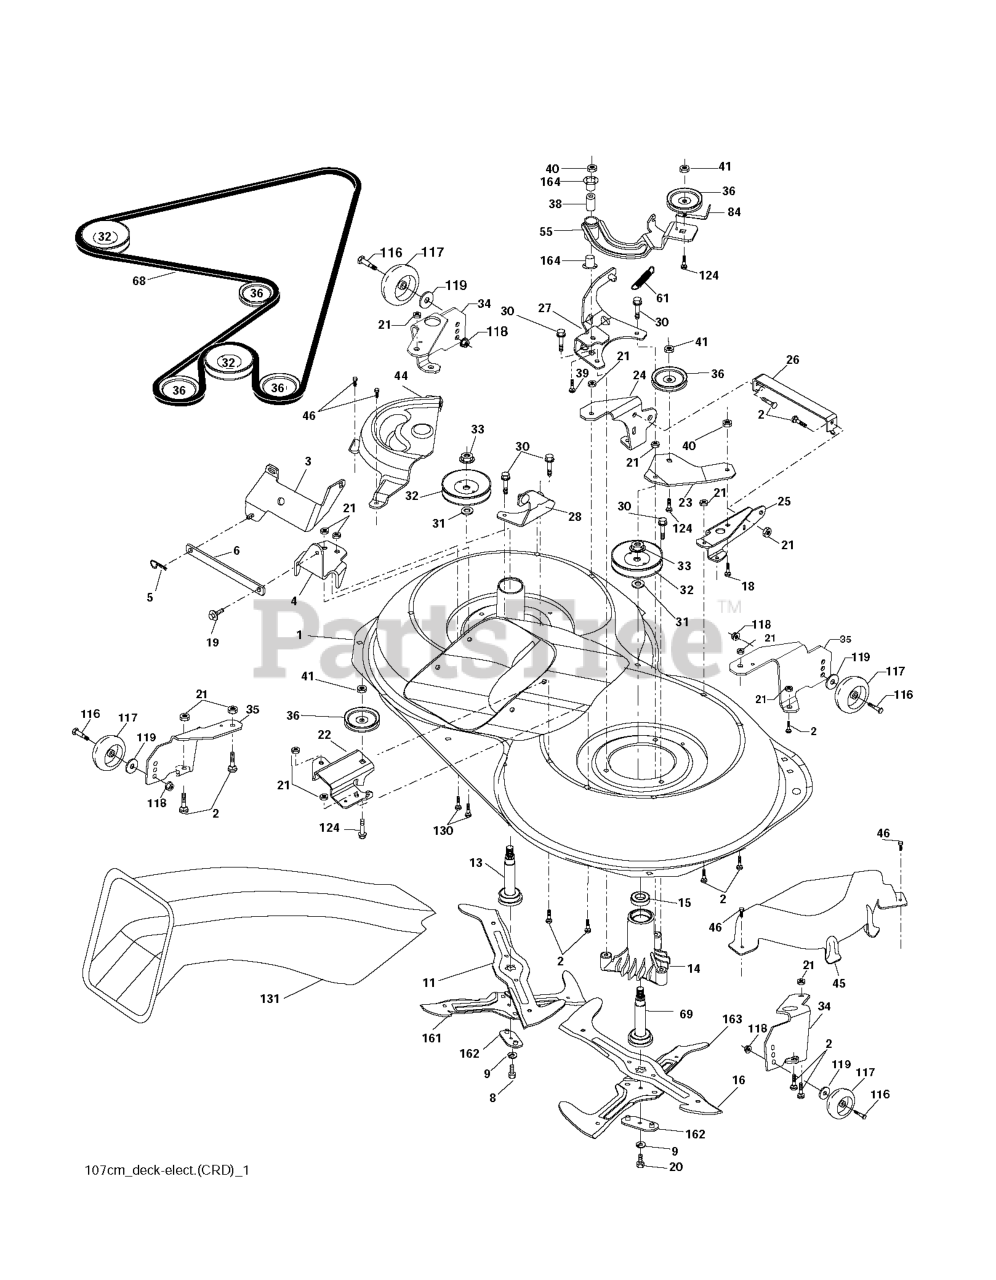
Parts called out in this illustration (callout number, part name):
1	Housing Asm. Mower 107 CRD
2	RP BOLT 5/16-18 X3/4 ZN/YEL GR
5	RETAINER-SPRNG RB
6	BAR.SWAY.92.CRD
8	BOLT.3/8-24X1.25 GR8
9	LOCKWASHER
11	BLADE.3N1.LH.CRD
13	SHAFT ASM VENT
14	HOUSING.MANDREL.VENTED (MACHD)
16	BLADE.3N1.RH.CRD
19	BOLT SHD 5/16-18
20	BOLT.3/8-24X1.25GR8. LHTHRD
21	LOCKNUT
22	BRACKET.IDLER.RR.107.CRD
24	BRACKET
25	BRACKET RF
26	SUPPORT
28	BRACKET
30	SCREW, WASHER HEAD
31	WASHER.SPACER.MANDREL
32	PULLEY.MANDREL.4.80 PD.2006
33	NUT.FLANGE.LOCK.TOP
34	BRACKET
35	BRACKET
36	PULLEY.IDLER.4.25
41	NUT LOCK FLG 3/8-16 UNC
45	COVER.MANDREL.RH.CRD
46	SCREW.1/4-20X5/8
55	ARM.IDLER.107.CRD
61	SPRING
68	HEX-BELT 107 MOWER
69	SHAFT.ASM.W/LWR.BRG.RH.THREAD
84	KEEPER, BELT IDLER
116	BOLT.SHOULDER.3/8-16X3-5/8.
117	RP WHEEL. GUAGE RALLY
118	NUT LOCK FLG 3/8-16 UNC
119	WASHER
124	BOLT.3/8-16X1.50
130	BOLT.CARR.SQNK.5/16-18UNC.X3/4
131	CHUTE BAGGER
163	BLADE.CROSS.RH.CRD.107
164	BRNG T
